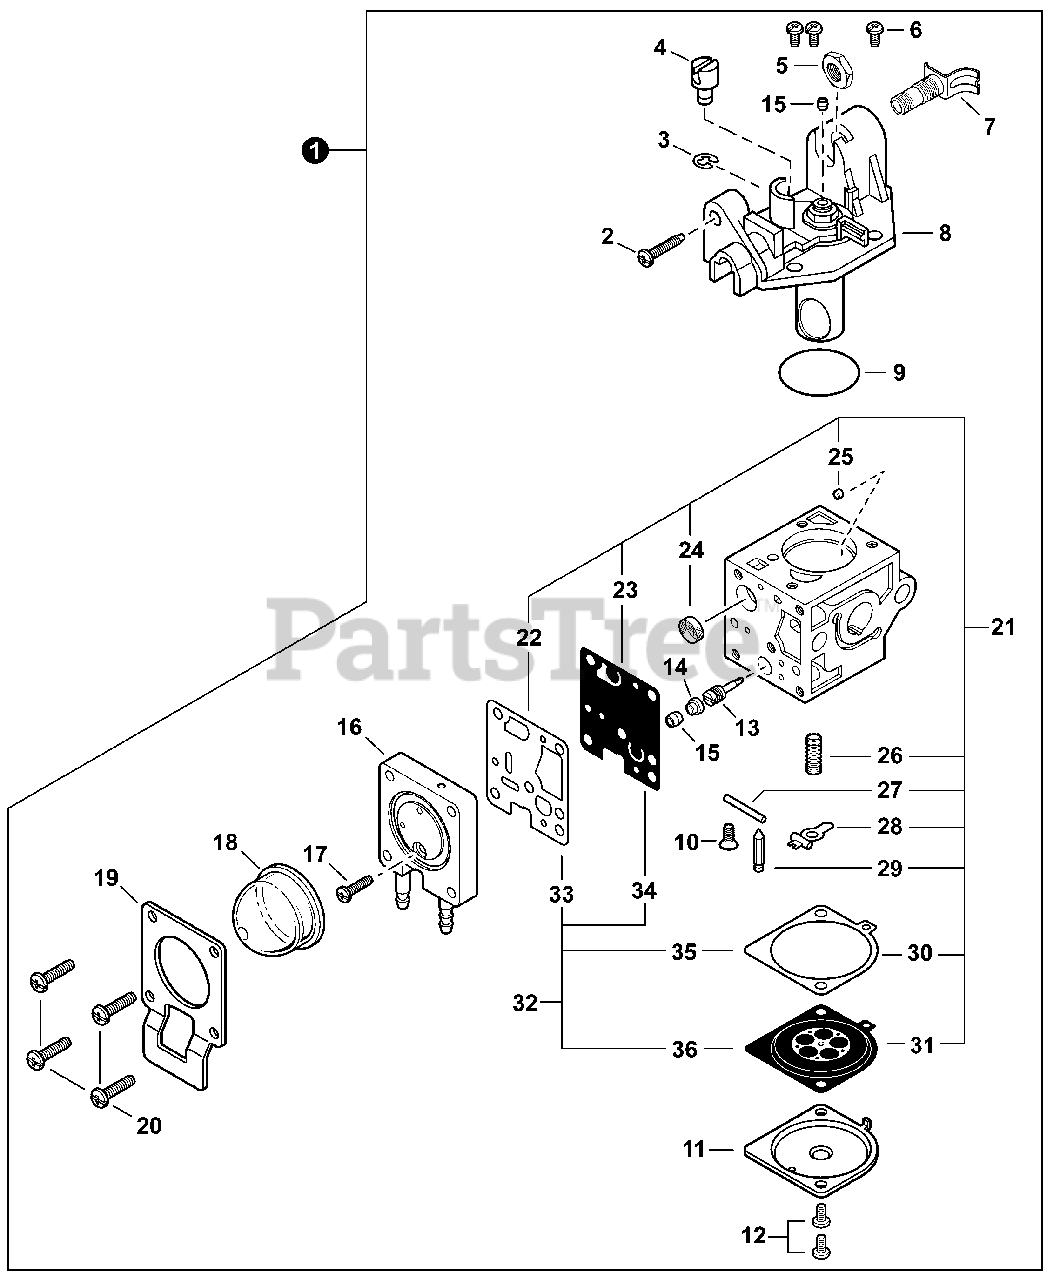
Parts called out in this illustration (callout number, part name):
1	CARBURETOR - RB-K106
2	SCREW, THROTTLE ADJUST
7	ADJUSTER, CABLE
8	COVER ASSY, ROTOR
11	COVER, METERING DIAPHRAGM
13	NEEDLE, HIGH SPEED
14	CAP, LIMITER
16	BODY ASSY, PURGE
18	BULB, PURGE
19	RETAINER, PURGE BULB
21	REPAIR KIT, CARBURETOR
22	GASKET, PUMP
23	DIAPHRAGM, PUMP
24	SCREEN, FUEL INLET
25	GUIDE, ROLLER
26	SPRING, METERING LEVER
27	PIN, METERING LEVER
28	LEVER, METERING
29	VALVE, INLET NEEDLE
30	GASKET, METERING DIAPHRAGM
31	DIAPHRAGM, METERING
32	GASKET / DIAPHRAGM KIT
33	GASKET, PUMP
34	DIAPHRAGM, PUMP
35	GASKET, METERING DIAPHRAGM
36	DIAPHRAGM, METERING
